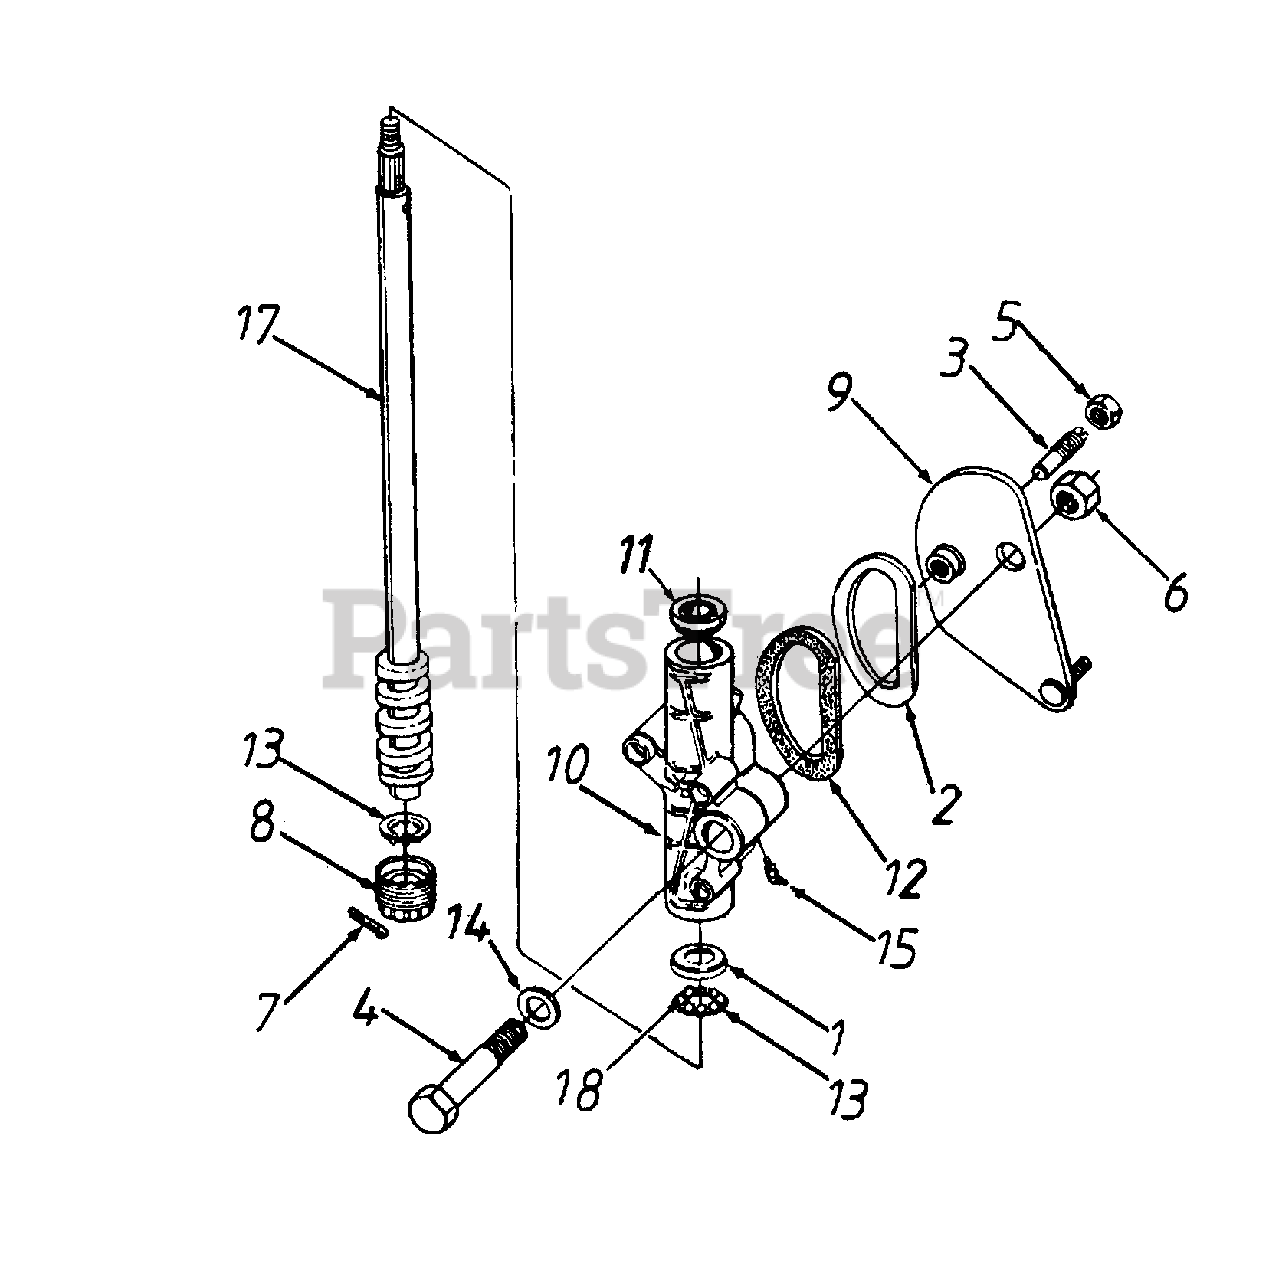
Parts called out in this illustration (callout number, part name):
1	Bearing Cup
2	Seal Retainer
3	Cam Follower
4	Pivot Shaft
5	Hex Jam Nut 9/16-18 Thd.
6	Hex Crown L-Nut 5/8-18 Thd.
7	Cotter Pin 1/8' Dia.
8	Adjustment Plug Ass'y.
9	Steering Arm Ass'y.
10	Steering Hsg. Bushing Ass'y.
11	Oil Seal
12	Seal
13	Ball Retainer
14	Fl-Wash. .781' I.D. x 1.25' O.D.
15	Grease Fitting
17	Steering Shaft Ass'y.
18	Ball Bearing
